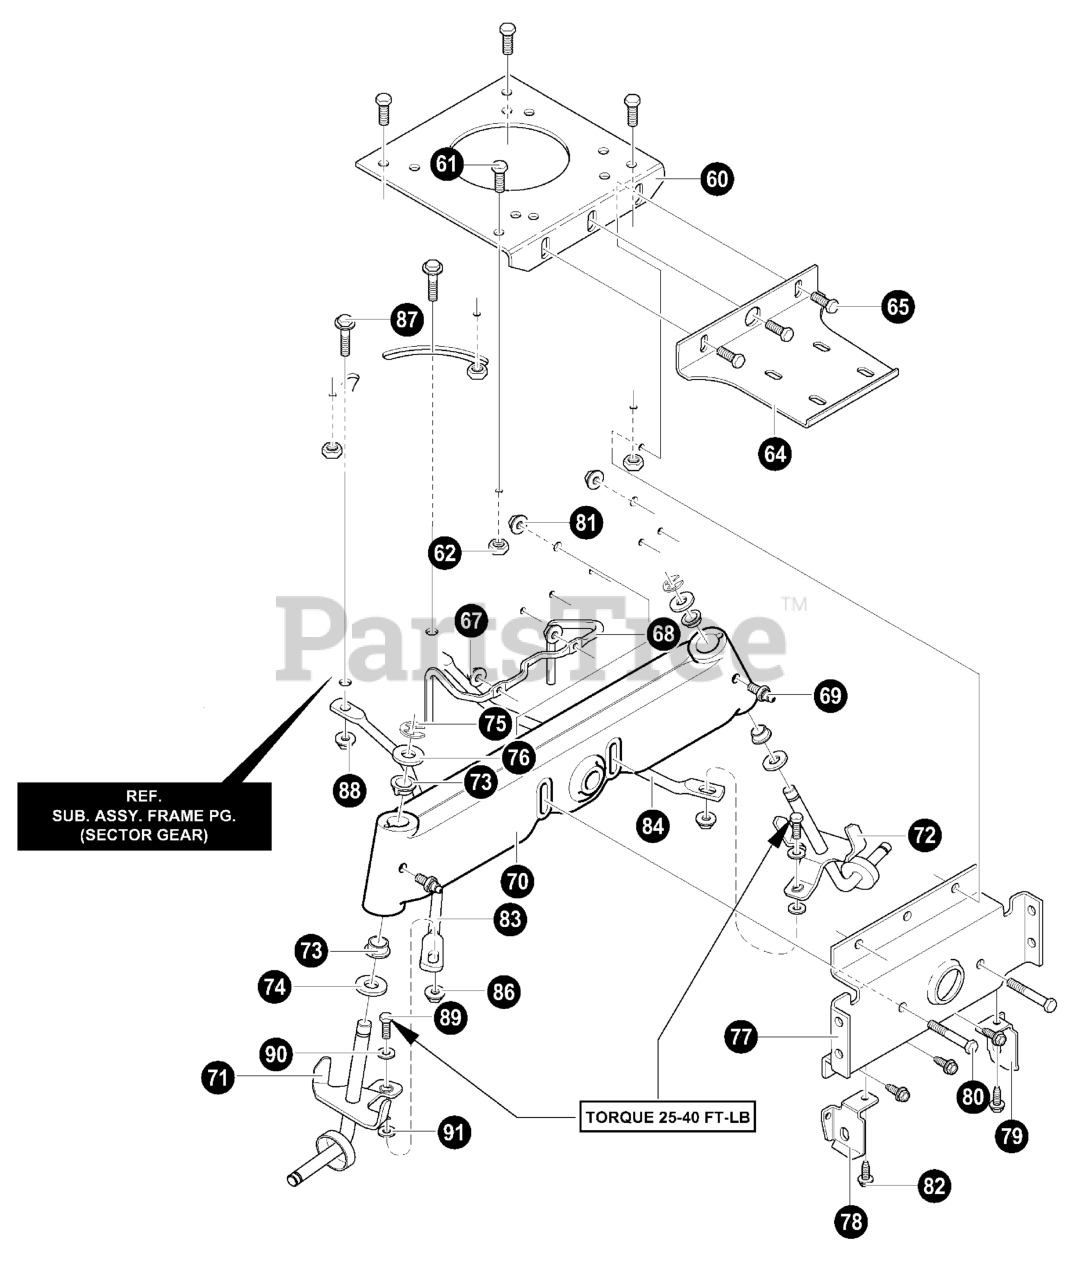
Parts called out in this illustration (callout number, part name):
60	ENGINE PLATE
61	SCREW, 5/16-18 x 0.75 HHWATAP
62	NUT, 5/16-18 WDFLLK 15X88
64	BRACKET, MUFFLER MOUNT
65	SCREW, 5/16-18 x 0.75 HHWATAP
67	NUT, 5/16-18 HEXWDFLLK WHIZ
68	GUIDE-STACK PULLEY BELT
69	ZERK, GREASE FITTING
70	AXLE, CAST MACHINED REBA
71	SPINDLE, LONG RH
72	SPINDLE, LONG LH
73	BEARING, SPINDLE
74	WASHER, .766IDX1.62ID
75	E-RING .574IDX.050X.750SH 11X3
76	WASHER, FLAT .765 x 1.81 x .059
77	HANGER, AXLE
78	HANGER, DECK RH
79	HANGER, DECK LH
80	SCREW, 5/16-18 x 3.00
81	NUT, 5/16-18 WDFLLK 15X88
82	SCREW, 5/16-18 x 0.75 HHWATAP
83	DRAG LINK RH
84	DRAG LINK LH
86	NUT, 3/8-16 HWDFLLK MACK 15X84
87	SHOULDER BOLT 9X57
88	NUT, 3/8-16 HWDFLLK MACK 15X84
89	SCREW, 3/8-16 x 1.50
90	WASHER FLAT .391X1.00X.083
91	WASHER FLAT .406X.81X16GA
